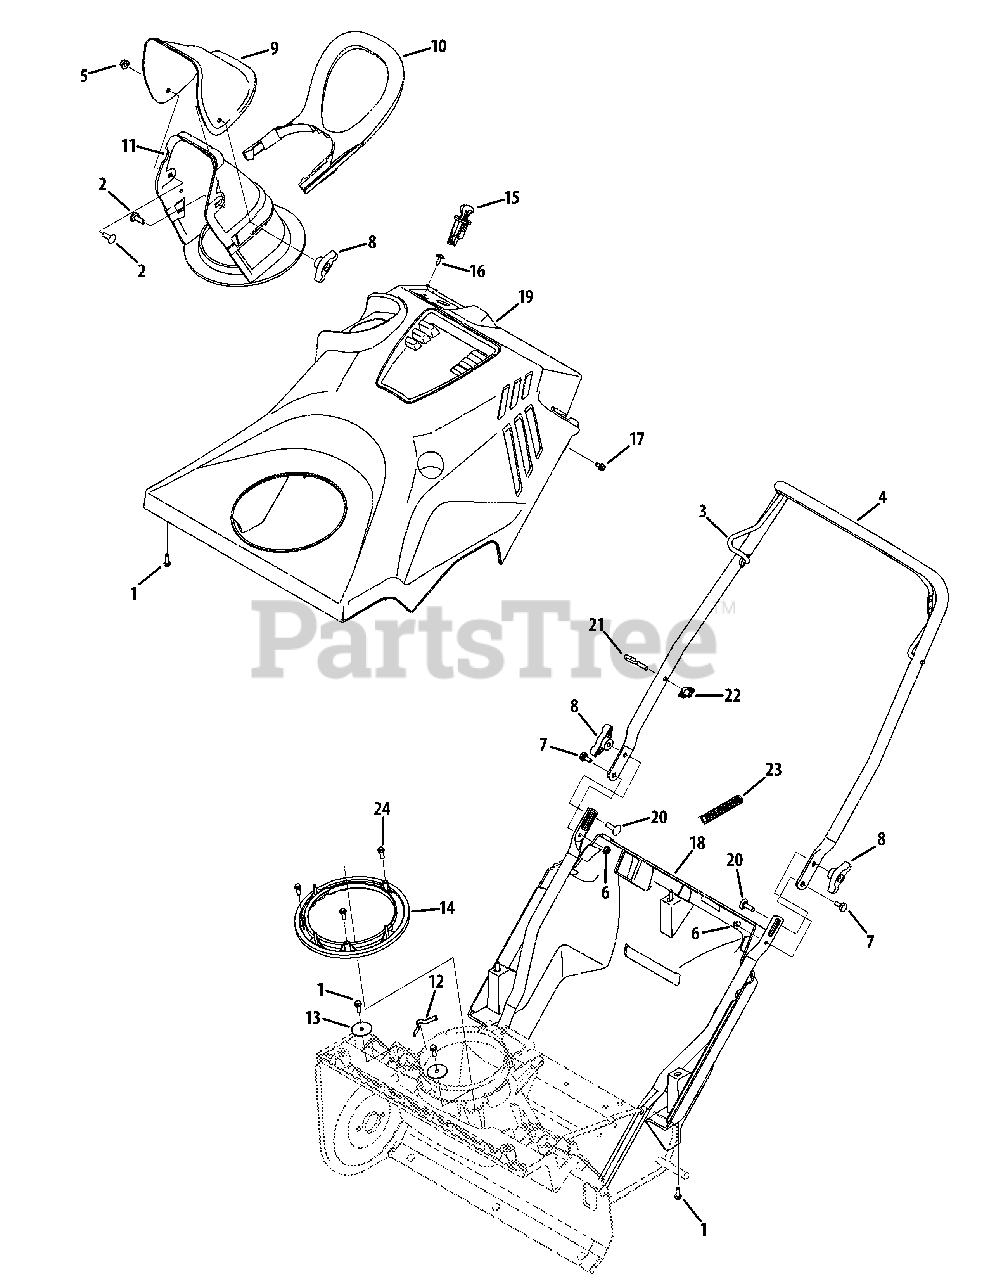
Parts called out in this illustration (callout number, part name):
1	Screw, 1/4-15 x 0.75
2	Carriage Bolt, 5/16-18 x .750
3	Auger Bail
4	Upper Handle
5	Flange Lock Nut, 5/16-18
6	Flange Lock Nut, 1/4-20
7	Shoulder Screw, 1/4-20 x .375 x .148
8	Wing Knob, 5/16-18
9	Upper Chute
10	Chute Handle
11	Lower Chute
12	Chute Adjustment Spring
13	Flat Washer, .28 x 1.51 x .066
14	Chute Ring
15	Ignition Switch Assembly
16	Hex Washer Screw, 1/4-15 x .50
17	Hex Washer Screw, 1/4-20 x .500
18	Bottom Cover
19	Top Cover
20	Carriage Screw, 5/16-18 x 1.00
21	Eye Bolt, 1/4-20
22	Handle Knob
23	Conduit
24	Hex Washer Screw, 1/4 x .750
